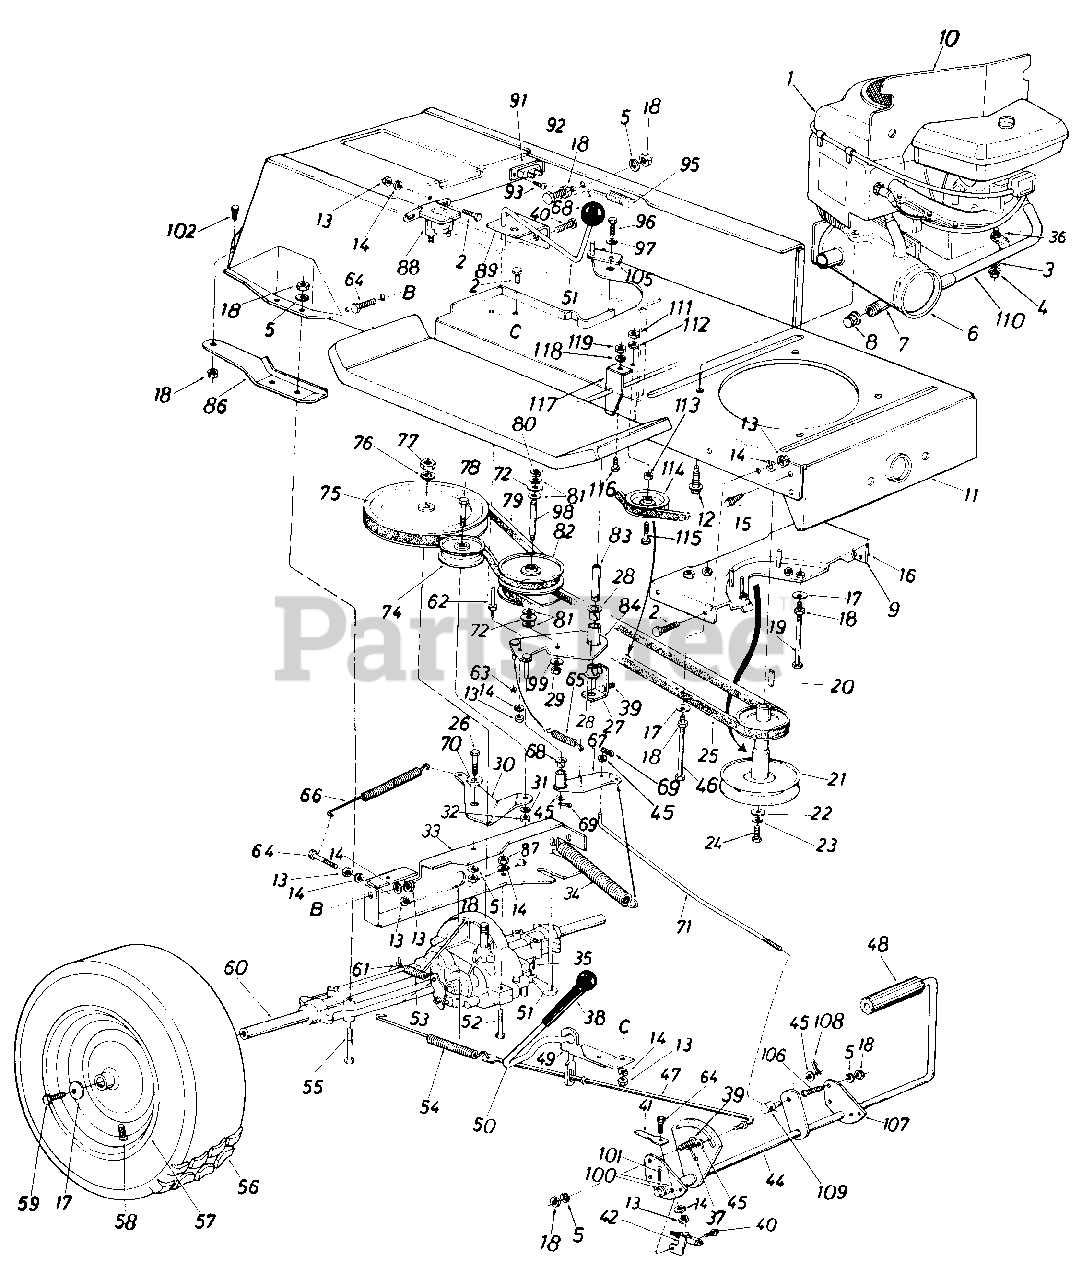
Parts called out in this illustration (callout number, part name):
2	Hex Bolt 1/4-20 x .62" Lg.
3	Special L-Wash. 5/16" I.D.
4	Hex Nut 5/16-18 Thd.
5	L-Wash. 5/16" I.D.
6	Exhaust Muffler
7	Pipe Nipple
8	Cap Oil Drain
9	Brake Cable Brk't.
10	Heat Shield
11	Lower Frame Ass'y.
12	Hex Wash. Hd. TT-Tap Scr. 3/8-16 x 1 25 Lg.
13	Hex Nut 1/4-20 Thd.
14	L-Wash. 1/4" I.D.
15	Hex Wash. Hd. AB-Tap Scr. 5/16" x .75" Lg.
16	Belt Guard Brk't. Ass'y.
17	Bell-Wash. .345" I.D. x .88"
18	Hex Nut 5/16-18 Thd.
19	Hex Bolt 5/16-18 x 4.00"
20	Sq. Key 1/4" x 1/4" x 2.00"
21	Engine Pulley
22	Fl-Wash. 7/16" I.D. x 1.25"
23	L-Wash. 7/16" I.D.
24	Hex Bolt 7/16-20 x 1.50" Lg.
25	Variable-Speed Belt .715 x 53" Lg.
26	Hex Bolt 5/16-18 x .75" Lg.
27	Bearing Shaft Bracket
28	Flanged Nyliner Brg. 5/8" I.D. x .88" Lg.
29	Hex Nut 3/8-24 Thd.
30	Idler Bracket
31	L-Wash. 3/8" I.D.
32	Hex Nut 3/8-24 Thd.
33	Transaxle Support Brk't.
34	Ext. Spring .94" O.D. x 6.7
35	Cotter Pin 1/8" Dia. x 1.0"
36	Fl-Wash. .34" I.D. x .62" O.D.
37	Cotter Pin 3/32" Dia. x 1.0"
38	Grip Black
39	Truss Mach. Scr. 5/16-18 x .75" Lg.
40	Hex Wash. Hd. Self-Tap Scr. 1/4-20 x .50" Lg.
42	Safety Switch
44	Clutch & Brake Pedal Ass'y.
45	Fl-Wash.
46	Hex Bolt 5/16-18 x 4.5"
47	Brake Rod
48	Foot Pad
49	Brake Lever Bracket
50	Hill Holder Brake Handle
51	Shift Lever Ass'y.
52	Hex Bolt 1/4-28 x 1.75" Lg.
53	Ext. Spring .38" O.D. x 2.5"
54	Ext. Spring .59" O.D. x 7.08"
55	Hex Bolt 5/16-18 x 2.50"
58	Air Valve
59	Hex Bolt 5/16-24 x .75" Lg.
60	Transaxle Complete
61	Brake Return Spring Anchor
62	Belt Guard Pin 1/4-20 Thd.
63	Cap Speed Nut 1/4" Dia.
64	Hex Bolt 1/4-20 x 1.0" Lg.*
65	Ext. Spring .50" Dia.
66	Ext. Spring .56" O.D. x 5.96"
67	Variable Speed Torque Brk't. Ass'y.
68	Flanged Bearing
69	Cotter Pin 3/32" Dia.
70	Shoulder Spacer .500" Dia. x .27" Lg.
71	Speed Control Link
72	Truss Bearing .56 Dia. x 1 .25"
74	Fl-Idler Pulley 3.25" x 1.0"
75	11/16" "V"-Pulley 8.0" O.D. x .501" I.D.
76	L-Wash. 1/2" I.D.
77	Hex Jam Nut 1/2-20 Thd.
78	Hex Bolt 3/8-24 x 1.50" Lg.
79	Variable Speed Belt .715 x 44" Lg.
80	Snap Ring .56" Dia.
81	Fl-Wash.
82	Variable Speed Pulley Ass'y. 5" O.D.
83	Bearing Shaft
84	Variable Speed Brk't. Ass'y.
86	Transaxle Support Brk't. R.H.
87	Hex Nut 1/4-28 Thd.
88	Solenoid
89	Shift Lever Bracket
91	Circuit Breaker
92	Hex Bolt 5/16-18 x 1.25" Lg.
93	Truss Hd. Phil. Scr. #10 x 1/z" Lg.
95	Ext. Spring .99" O.D. x 11.0'
96	Hex Bolt 3/8-24 x .75" Lg.
97	Bell-Wash. .38" I.D. x .88"
98	Shaft .56" Dia. x 3.875" Lg.
99	Bell-Wash. .39" I.D. x 1.12"
100	Fl-Wash.
101	Cotter Pin
102	Hex Wash. Hd. Scr. 5/16-18 x .62" Lg.
105	Belt Guard
106	Truss Mach. Scr. 5/16-18 x .75" Lg.
107	Pedal Bracket
108	Hairpin Cotter 118" Dia.
109	Ferrule
110	Inlet Tube Ass'y.
111	Hex Nut 3/8-16 Thd.
112	L-Wash. 3/8 I.D.
113	Fl-Wash. .390" I.D. x 1.12" O.D. x .187
114	Fl-Idler w/Flanges 2.750
115	Hex Bolt 3/8-16 x 2.00" Lg.
116	Hex Bolt 1/4-20 x .62" Lg.
117	Spring Hanger Bracket
118	L-Wash. 1/4" I.D.
119	Hex Nut 1/4-20 Thd.
